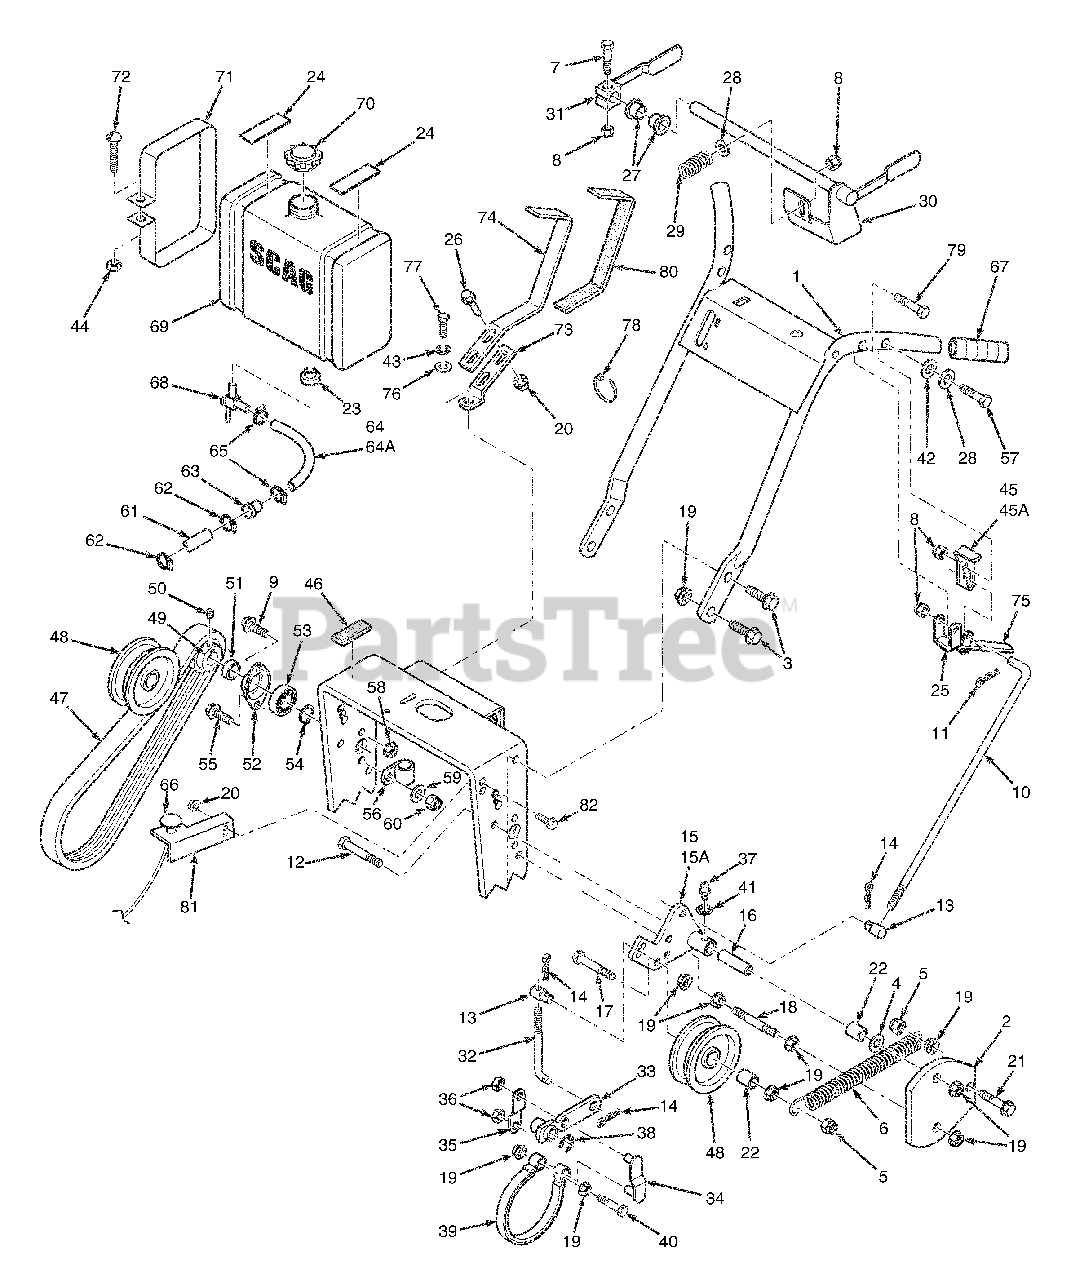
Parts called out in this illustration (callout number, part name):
1	Handle Assembly
2	Belt Guard
3	Capscrew, 3/8-16 x 1" Ser. Flange
4	Washer, 3/8" (.391 x .938 x .105)
5	Nut, 3/8-16 Elastic Stop
6	Spring, Idler
7	Bolt, 5/16-18 x 1-1/4" Hex Head
8	Nut, 5/16-18 Elastic Stop
9	Capscrew, 1/4-20 x 3/4" Hex Head
10	Control Rod, Steering
11	Hair Pin, Small
12	Bolt, 3/8-16 x 4-1/2" Hex Head
13	Swivel Joint
14	Hair Pin, Large .094 Diameter
15	Idler Bracket, RH
15A	Idler Bracket, LH
16	Idler Sleeve
17	Bolt, 3/8-16 x 3/4" Hex Head
18	Support Belt Guard
19	Nut, 3/8-16 Serrated Flange
20	Nut, 5/16-18 Serrated Flange
21	Cpscrw, 3/16-18 x 1-1/4" Ser. Flng.
22	Spacer
23	Bushing
24	Rubber Pad, (Upper)
25	Steering Lever
26	Capscrew, 5/16-18 x 1" Ser. Flng.
27	Bushing
28	Washer, 5/16 (.375 x .875 x .083)
29	Spring, Operator Presence
30	Operator Presence Lever,
31	Operator Presence Lever, RH
32	Brake Rod
33	Brake Lever
34	Brake Link
35	Brake Link Plate
36	Nut, 3/8 Push-on
37	Grease Fitting, Straight 1/4-28
38	Retaining Ring, 5/8 Ext. "E"
39	Brake Band
40	Bolt, 3/8-16 x 2" Hex Head
41	1/4" Internal Tooth Lockwasher
42	Curved Spring Washer
43	Socket Head Capscrew #8-32 x 1/2"
44	Nut, 1/4-20 Hex
45	Neutral Latch, RH
45A	Neutral Latch, LH
46	Rubber Pad (Lower)
47	Belt, Wheel Drive
48	Idler Pulley, Wheel Drive
49	Pulley, Jackshaft (Inc. 50)
50	Setscrew, Hex Socket Knurl Cup Pt. 5/16-18 (nylock)
51	Spacer, Jackshaft Pulley
52	Flange, Jackshaft Bearing
53	Bearing, Jackshaft
54	Retaining Ring, 5/8 Ext. Basic
55	Capscrew, 1/4-20 x 1" Ser. Flange
57	Bolt, 5/16-18 x 2" Hex Head
58	Nut, 1/4-20 Serrated Flange
59	Flatwasher, 5/16 (.375 x .875 x .083)
60	Nut, 1/4-20 Elastic Stop
64	Fuel Hose,1/4" ID, 10" (KH Only)
65	Clamp, Fuel Hose
67	Grip, Handle
68	Valve, Fuel Shut Off
69	Fuel Tank Assy.
70	Fuel Tank Cap
71	Strap, Fuel Tank
72	Screw, 1/4-20 x 2" Rnd Hd Slotted
73	Shift Lever
74	Shift Lever Extension
75	Grip, Steering Lever
76	Washer, 3/8 (.391x .938 x .105)
77	Nut, 3/8-24 UNF
78	Cable Tie
79	Bolt, 5/16-18 x 2-1/2"
80	Grip, Shift Handle
82	Capscrew, 5/16-18 x 3/4" Ser. Flange
